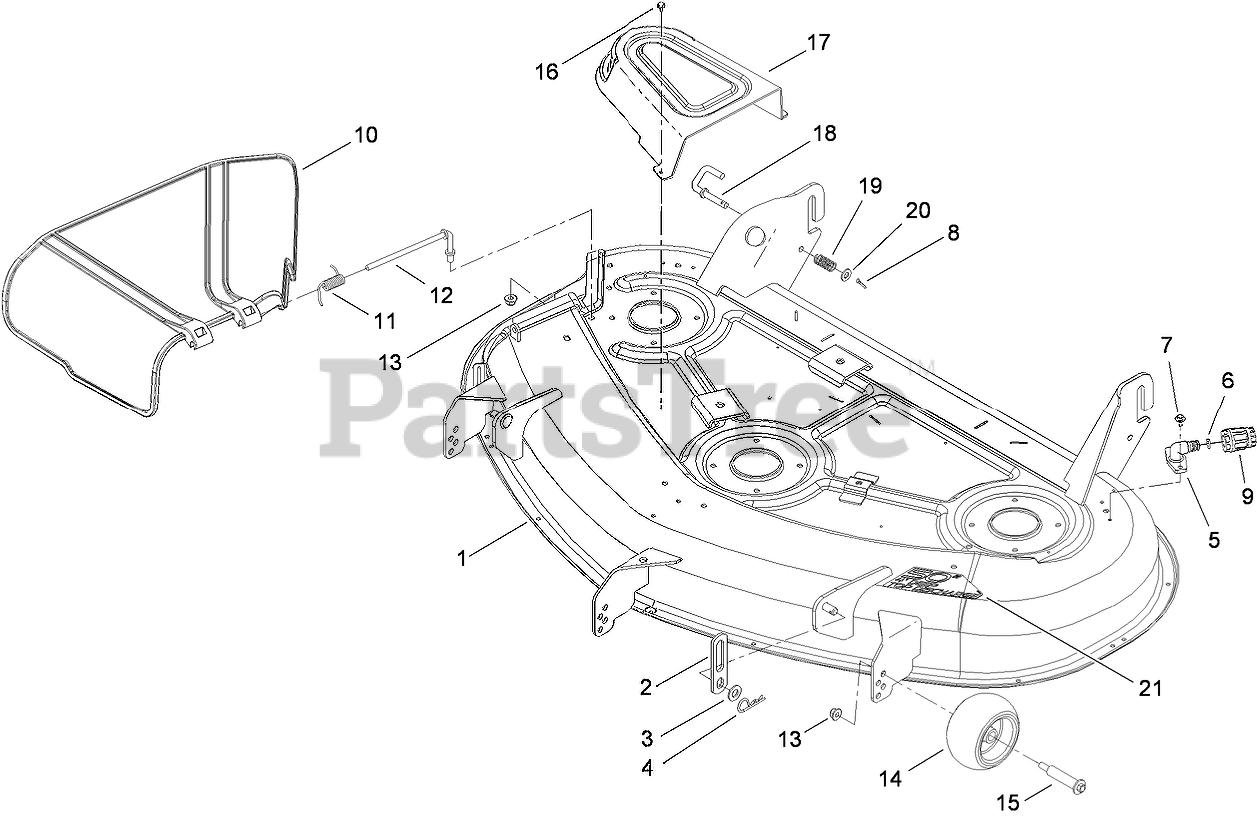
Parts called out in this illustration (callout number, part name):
1	50 INCH DECK ASM
2	LINK-LIFT
3	WASHER-FLAT
4	PIN-COTTER
5	FITTING-WASHOUT
6	O-RING
7	SCREW-HHFTF
8	PIN-COTTER
9	CONNECTOR-HOSE
10	DEFLECTOR
11	SPRING-TORSION
12	ROD-PIVOT
13	NUT-HF, NI
14	ROLLER-SCALP, ANTI
15	BOLT-SHOULDER
16	SCREW-HWHTF
17	COVER-BELT
18	PIN-LATCH
19	SPRING-COMPRESSION
20	WASHER-FLAT
21	DECAL-50 INCH
